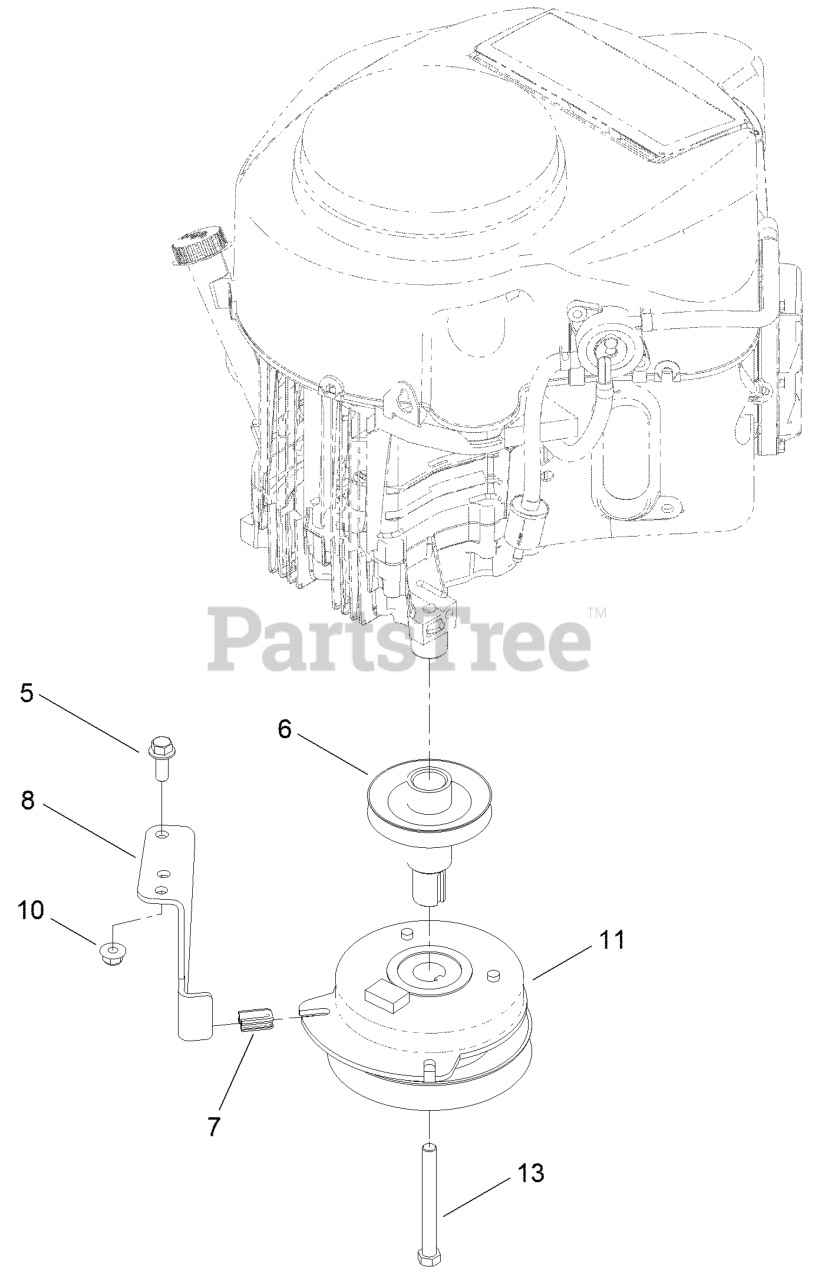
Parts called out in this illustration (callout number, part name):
5	SCREW-HHF 3/8-16 X 1
6	PULLEY-ENGINE
7	ISOLATOR-CLUTCH
8	STOP-CLUTCH
10	NUT-HF, NI
11	CLUTCH-ELECTRIC, PTO
13	SCREW-HH
